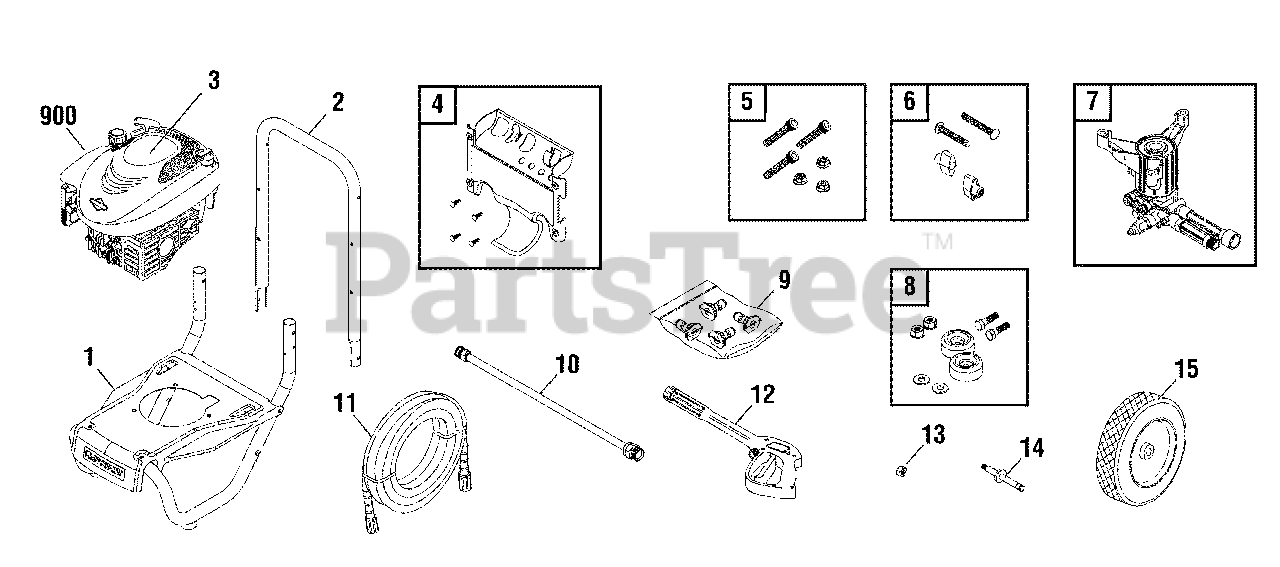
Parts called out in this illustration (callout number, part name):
5	KIT, Hardware, Pump Mounting
6	KIT, Hardware, Handle
7	PUMP
8	MOUNT, Vibration
9	KIT, QC Nozzles
10	EXTENSION, QC
11	HOSE
12	GUN
13	NUT
14	AXLE
